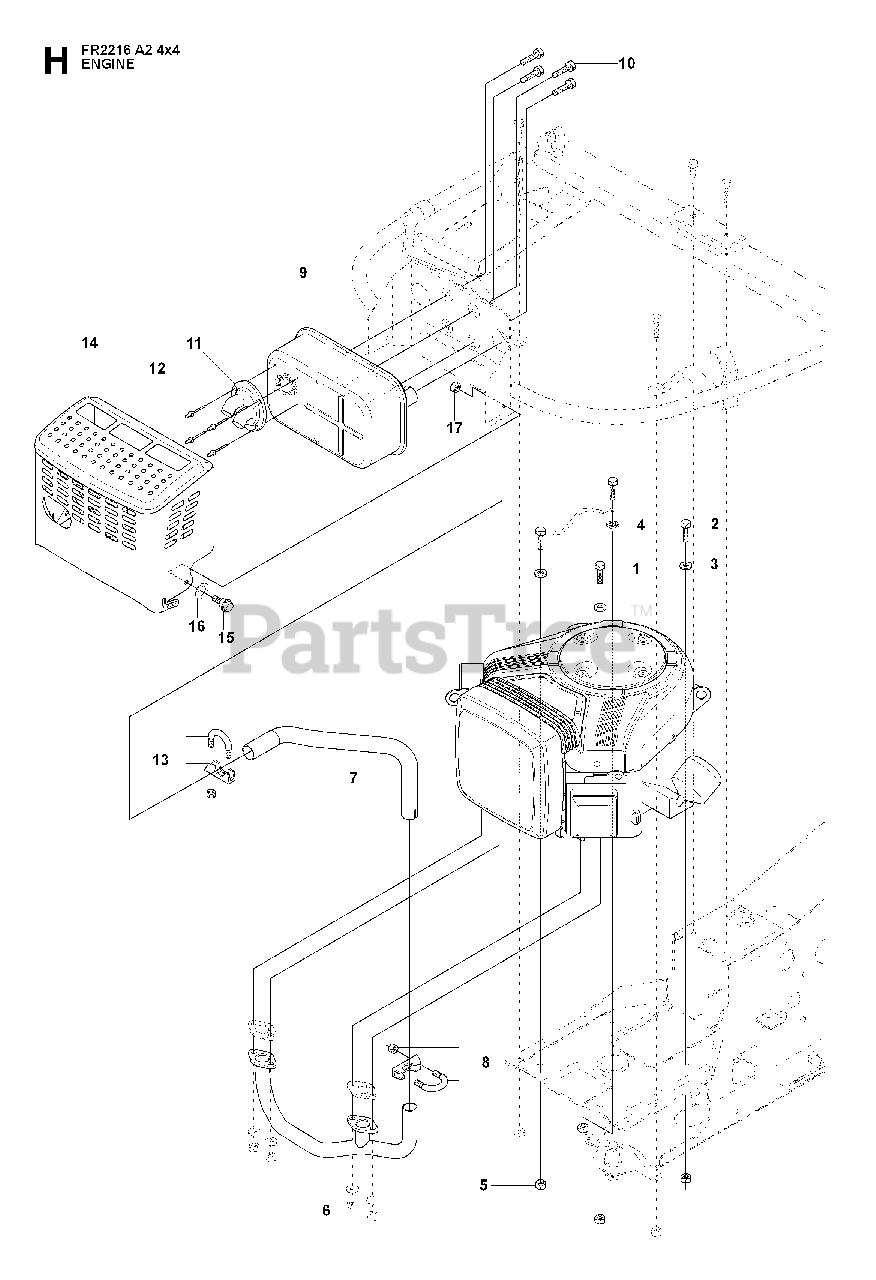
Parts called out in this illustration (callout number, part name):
3	WASHER BRB 8.4X17
5	LOCKNUT M8
16	SPRINGWASHER
17	LOCKNUT M8
